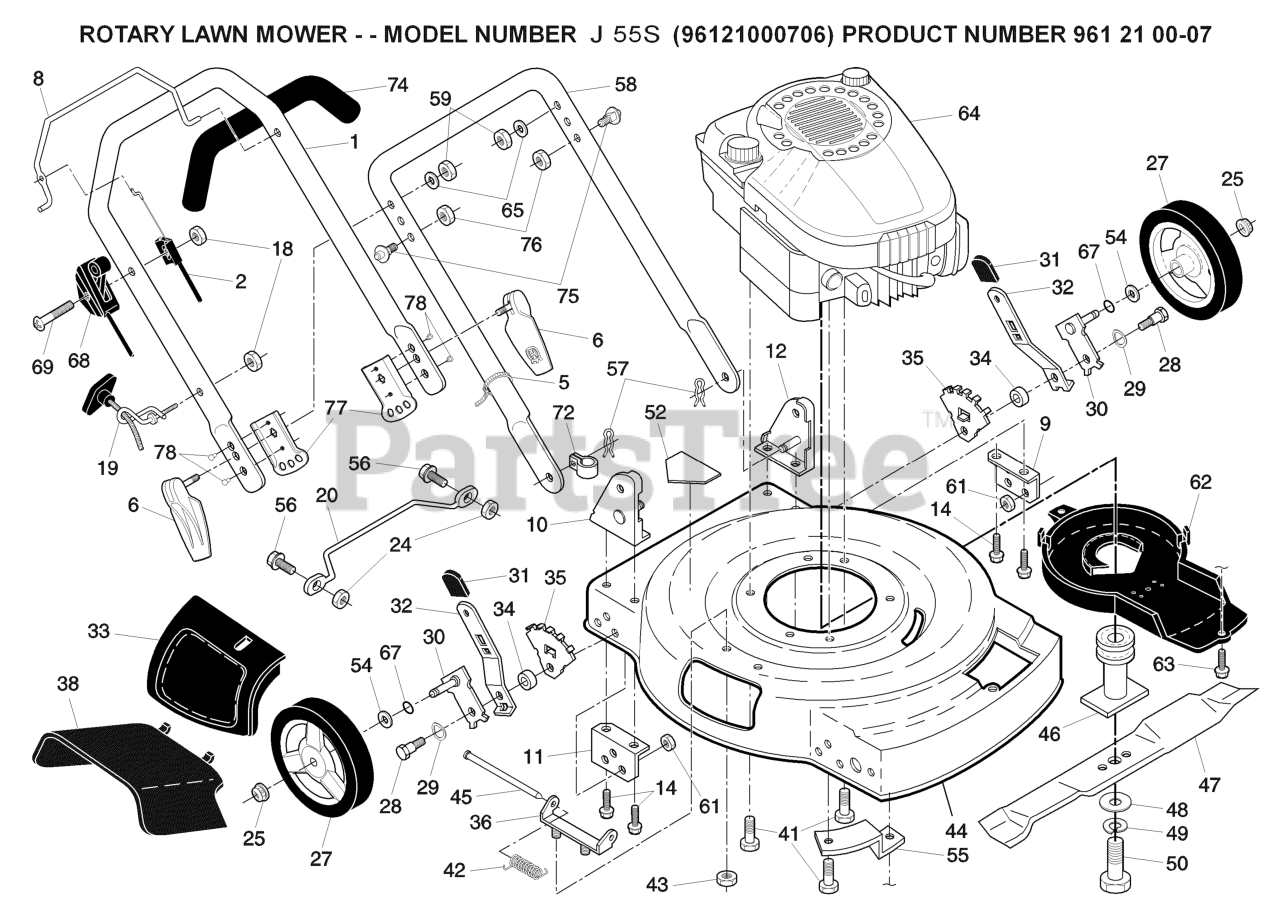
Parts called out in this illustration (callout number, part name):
2	ENGINE ZONE CONTROL CABLE
5	TIE GUIDE
6	ASM.QUICK.RELEASE
8	BAIL.COMF.FWGD.668.ORANGE.WALK
9	GUARD.SLKSCR.BELT.
10	HANDLE BRACKET ASM. RH
11	Support Bracket, Handle, RH
12	HANDLE BRACKET ASM. LH
14	SCREW.5/16-18X3/4
18	NUT
19	RB GUIDE.ROPE.STD.BLK.ZIN WSL
25	NUT.HEX.FLANGE.3/8-16.LO(3 2)
27	WHEEL & TIRES ASSY, FRONT
28	BOLT SHOULDER 3/8 -16X1
29	WASHER.CURVED.CYLINDRICAL
30	AXLE ARM ASSY.
31	SELECTOR KNOB
32	SPRING.SEL.EXT.21.DOMED.12/14
33	DOOR.MULCH.22.EZ.MULCH.GREY
34	SPACER.HEIGHT.ADJUSTER
35	BRACKET.ADJ.WHEEL.5POS.ADS
36	BRACKET.ASM.HOUSING.EZ.MUL
38	DEFLECTOR.GUARD.22..EZ.MULCH
41	BOLT 3/8-16X1-1/8
42	TORSION SPRING
43	LOCKNUT.NYLOC.1/4-20
44	Kit, Mower Housing
45	ROD.HINGE.COMBI-C
46	BLADE ADAPTOR / PULLEY
47	Blade, 22"
48	WASHER,HARDEN
49	LOCKWASHER
50	SCREW, HEX HD 3/8-24 X 1-3/8
52	DECAL.INTERNATIONL.CUTFINGER
54	WASHER.FLAT.1/2
55	BRACKET
56	REPL BY 817 02 10-08
57	HAIRPIN COTTER
58	HANDLE LOWER EZ 2POS GRAY
59	Locknut, Hex 1/4-20
61	LOCKNUT
62	DEBRIS SHIELD
63	SCREW.HEX.WSH
65	WASHER.20X8.5
67	O-RING..070X.487.NEOPRENE
68	Control Throttle
72	CLIP.CABLE.BLK
74	GRIP.HANDLE.FOAM
75	STUD.QUICK.ADJUST
76	NUT.LOCK.5/16-18
77	BRACKET.ADJ.3POS.GREY
